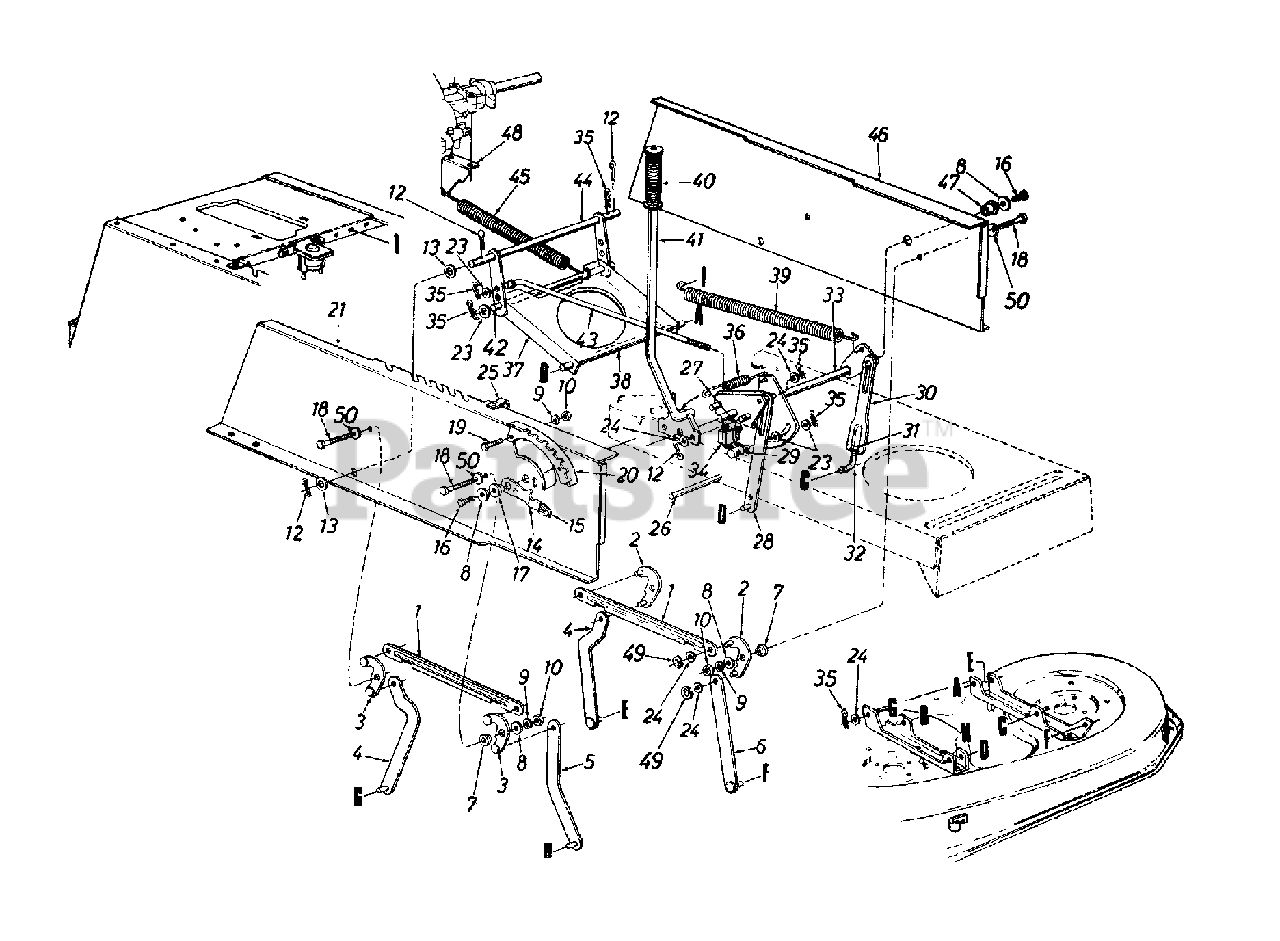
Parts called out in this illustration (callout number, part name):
3	Pivot Link Ass'y. - R.H.
7	Shld. Spacer .318" I.D.
8	Fl-Wash. .344" I.D. x .62" O.D.
9	L-Wash. 5/16" I.D.
10	Hex Nut 5/16-18 Thd. (Gr. 5)
12	Cotter Pin 1/8" Dia.
13	Fl-Wash. .635" I.D. x 1.0" O.D.
14	Height Adj. Stop Lever Ass'y.
16	Hex Wash. TT-Tap Scr.5/16-18 x
17	Flange Brg. .63" I.D.
18	Hex Wash. Hd. Scr. 5/16-18 x .875" Lg.
19	Hex Bolt 5/16-18 x .75" Lg.
20	Index Brkt.
24	Fl-Wash. .531" I.D. x .93" O.D.
26	Running Board Rod
27	Hex Wash. Hd. Tap Scr.
31	Hex Nut 1/2-20 Thd. (Gr. 5)
32	Lift Link Adjuster
35	Inter. Cotter Pin 3/8" Dia.
36	Extension Spring
39	Extension Spring
40	Grip (Lift Handle)
43	Disengagement Rod
49	"E"-Ring
50	Bell-Wash. .325" I.D.
97675A-0637	LIFT HANDLE ASSY POWDER BLACK - POWDER BLACK (0637)
97675A-0638	LIFT HANDLE ASSY POWDER BLACK - MTD/TROY-BILT RED (0638)
97675A-0648	LIFT HANDLE ASSY POWDER BLACK - TECH GRAY (0648)
97675A-0665	LIFT HANDLE ASSY POWDER BLACK - YARDMAN GREEN (0665)
